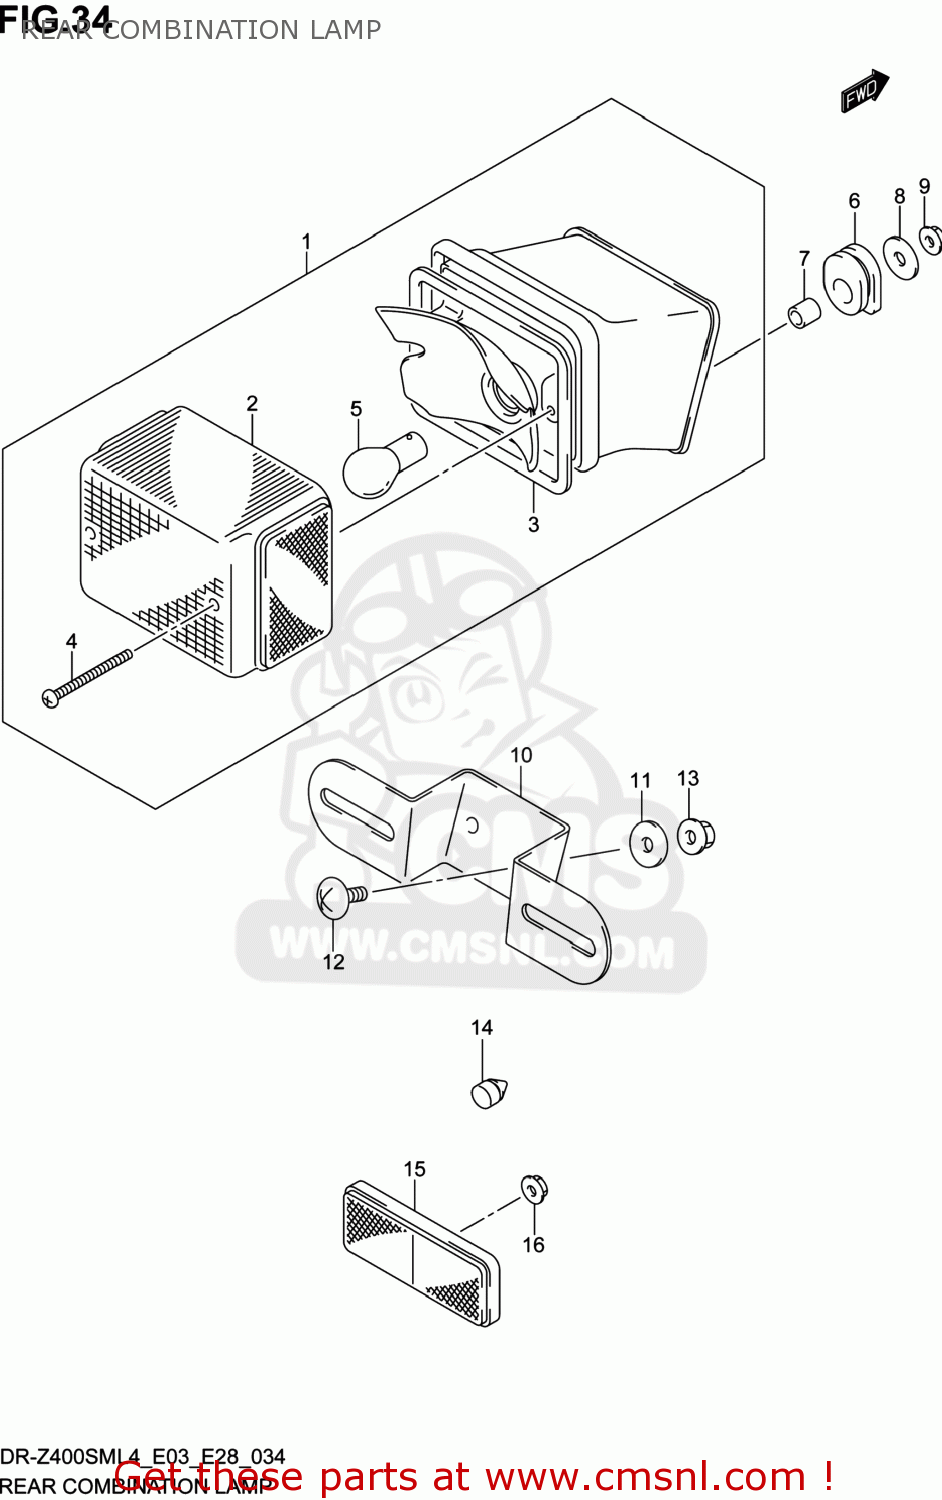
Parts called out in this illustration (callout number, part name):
1	LAMP ASSY,RR COMBINATION
2	LENS
3	GASKET,LENS (NAS)
4	SCREW(4X45)
5	BULB(12V21/5W)
6	CUSHION,RR COMBINATION
7	SPACER(6.5X10X10)
8	WASHER(6.5X20X1.6)
9	NUT
10	BRACKET,LICENSE PLATE
11	WASHER(6.5X20X1.6)
12	SCREW
13	NUT
14	CUSHION
15	REFLECTOR ASSY,RR
16	NUT
